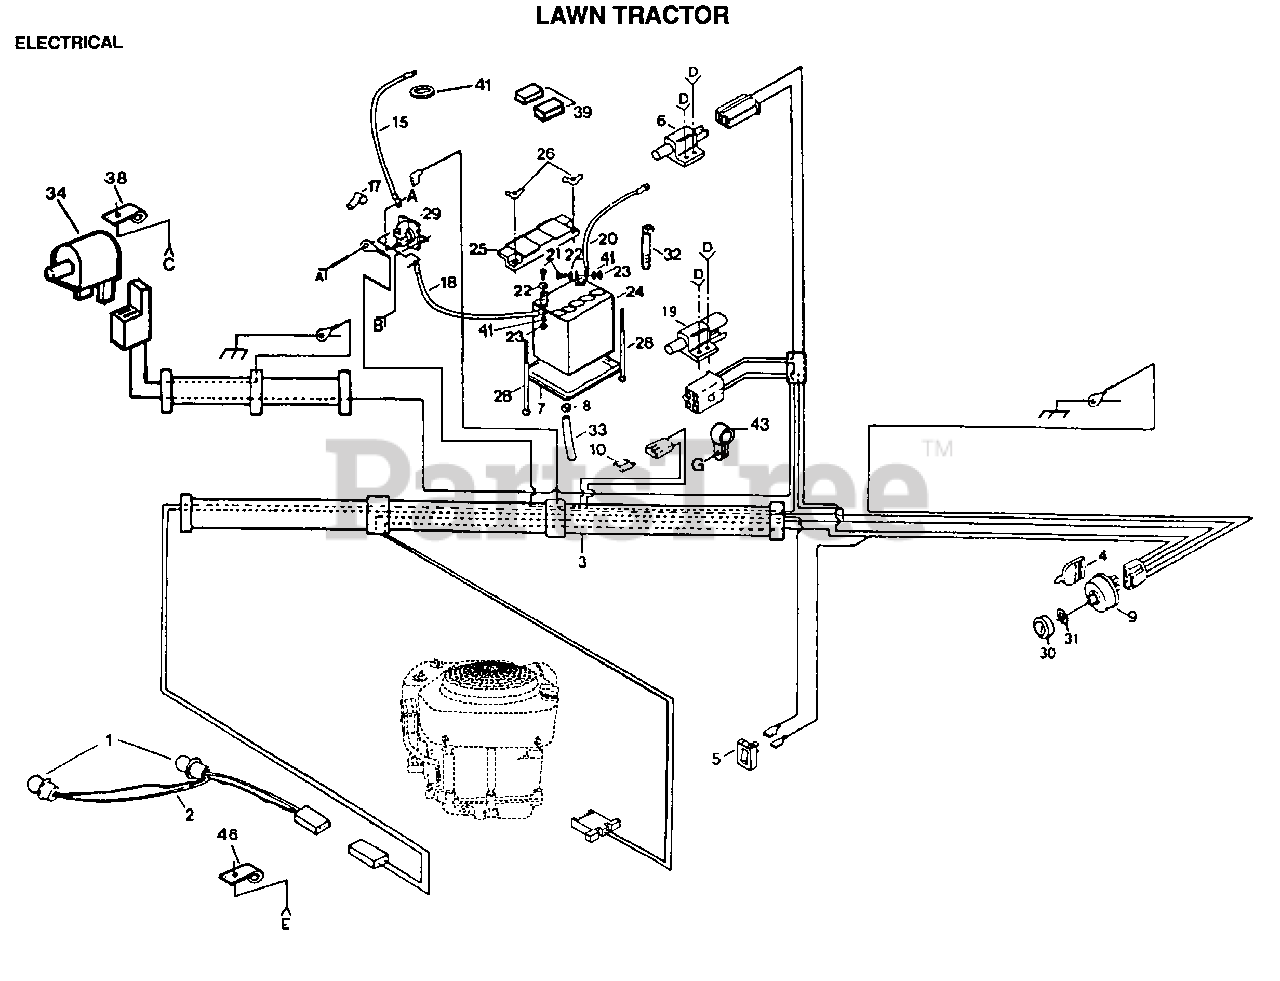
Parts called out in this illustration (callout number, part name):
2	HARNESS T
3	HARNESS,IGNITION
5	SWITCH LT
6	SWITCH-INTER. GT
7	"TRAY T, BATTERY"
8	HOSE CLAMP T
10	FUSE HYT
17	COVER, TERMINAL
18	STARTER CABLE GT
19	SWITCH INTERLOCKT
21	BOLT LT
22	WASHER
28	BOLT
32	WIRE TIE
34	SWITCH SEAT
39	"CAP,BATTERY "
41	LOCKWASHER
43	INSUL CLIP T
46	CLIP T
